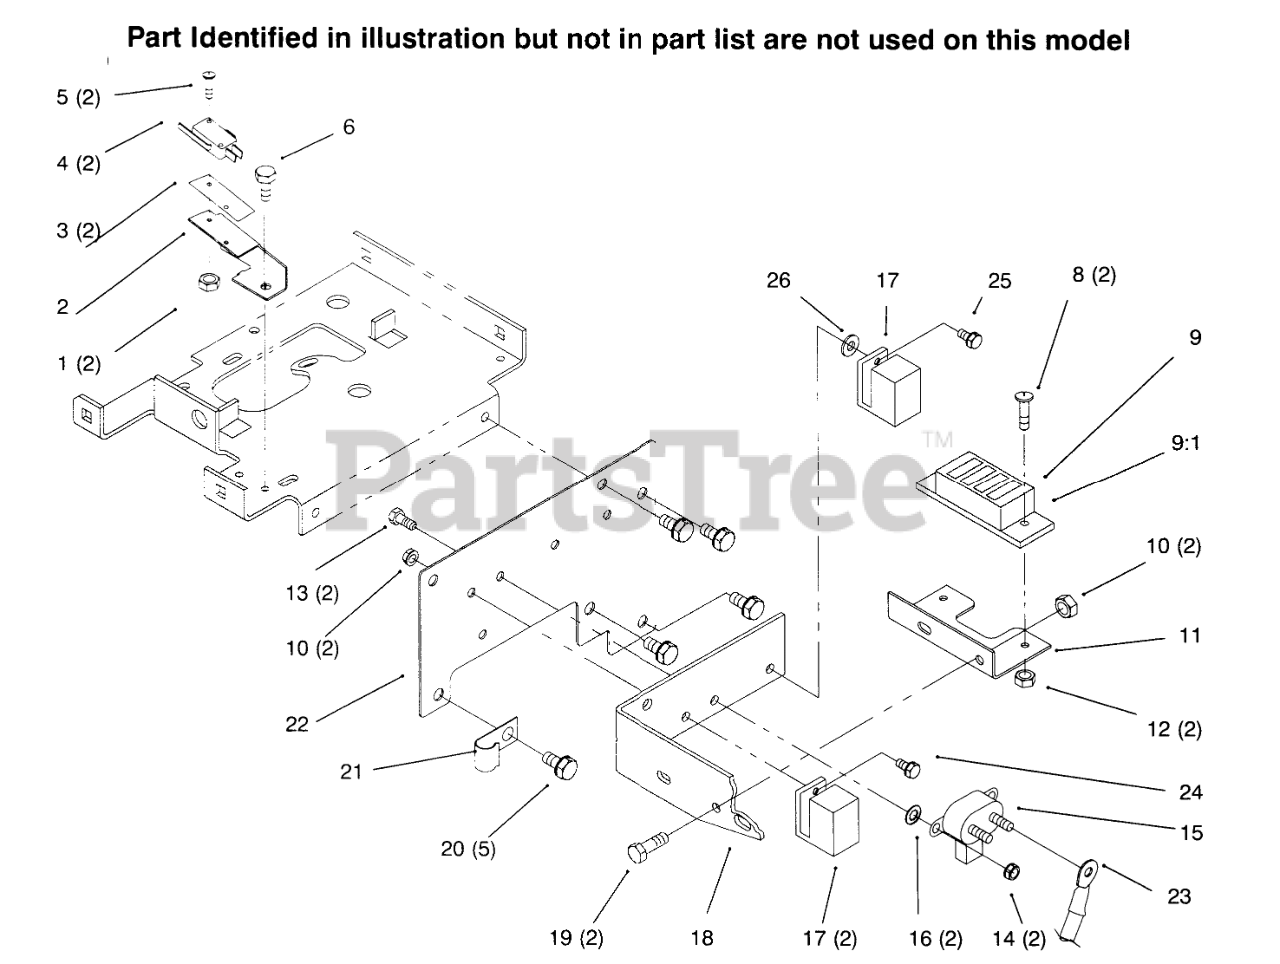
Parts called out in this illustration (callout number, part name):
1	NUT-HEX
2	BRACKET-SWITCH
3	BARRIER - SWITCH
4	SWITCH
5	SCREW-PHL 4-40X1 1/4
6	SCREW-HWH
8	SCREW-PAN
9	WIRING HARNESS & DIA
9:1	FUSE-HOLDER 4 WAY
10	NUT-LOCK, NI
11	FUSE HOLDERB
12	Nut
13	SCREW1/4-20X5/8 WHIZ
14	NUT-HEX
15	Solenoid
16	WASHER-LOCK/EXT
17	RELAY
18	BRACKET-BELTB
19	SCREW-HH
20	Bolt
21	CLIP
22	Front Plate
23	ASSY WIRE
